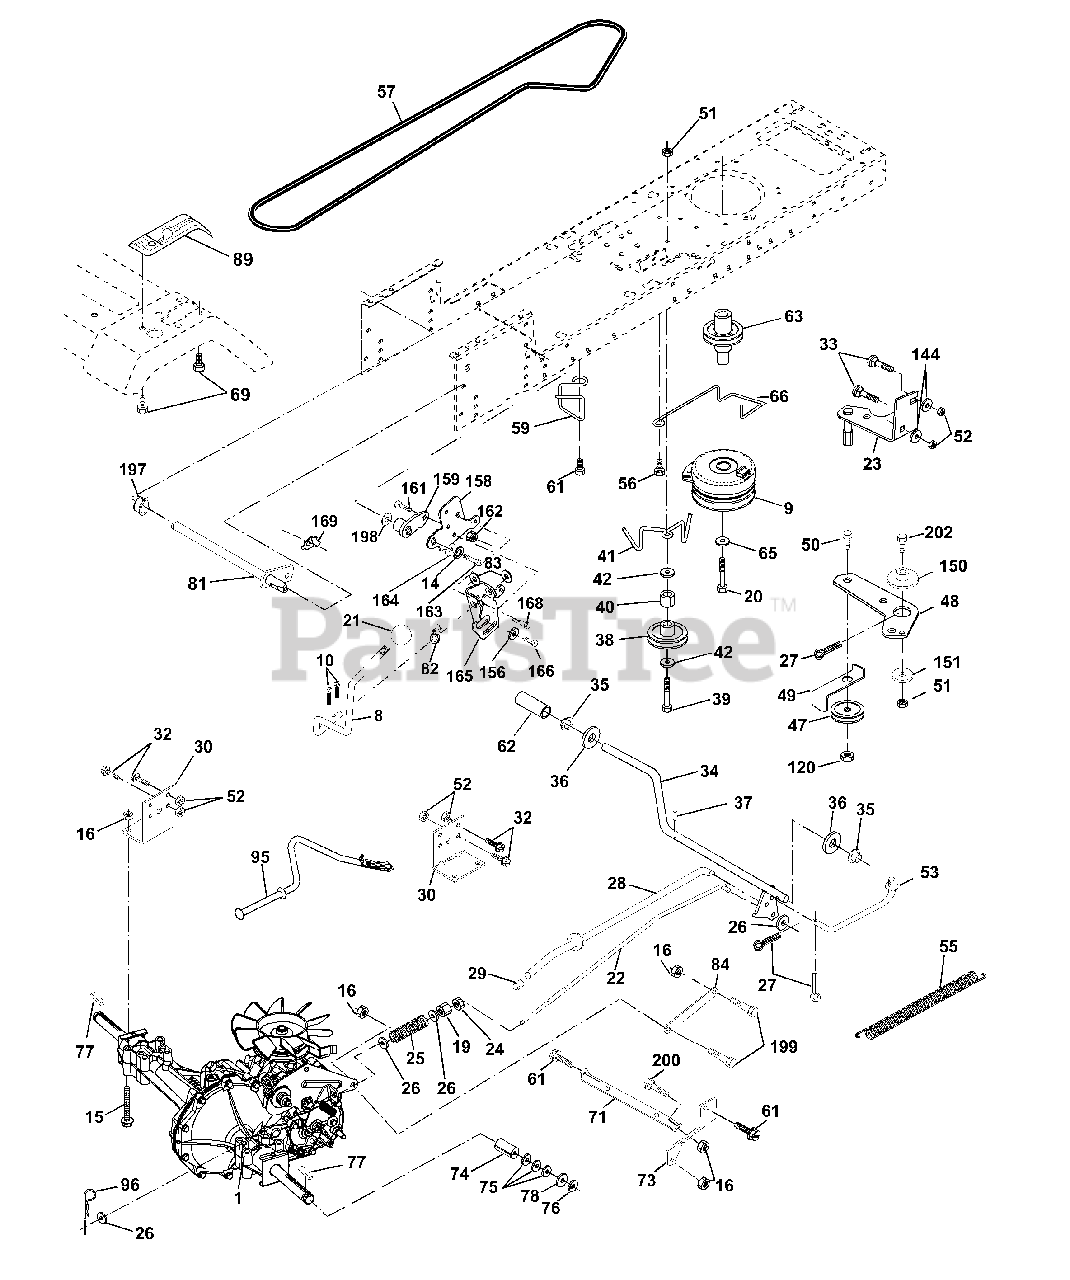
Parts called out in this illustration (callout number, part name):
8	Rod Shift Fender Adjust LT
9	Clutch Elecric
10	Pin Cotter 1/8 x 1 CAD
14	Washer Lock Hvy Helical
15	Bolt Hex 5/16-18 Gr. 5
16	Nut Lock Hex W/Ins. 5/16-18 Unc P
19	Nut Lock Hex W/Ins 3/8-16 Unc
20	Bolt, Hex 7/16-20 x 4-1/4 Ga. 5
21	Knob Deluxe 1/2-13 UNC BLK/BLK
22	Rod, Brake Hydro
23	Bracket Asm. Anti-Rot EVX
24	Nut Hex Jam 3/8-16 UNC
25	Spring, Brake Rod
26	Washer
27	Pin Cotter 1/8 x 3/4 CAD.
28	Rod, Parking Brake
29	Cap,Parking Brake
30	Bracket, Transaxle
32	Bolt Hex Hd 5/16-18 Unc x 3/4
33	Bolt Carriage 5/16-18 UNC x 3/4
34	Shaft, Foot Pedal
35	Bearing, Nylon
37	Pin, Roll
38	Pulley Flat Composite
39	Bolt Fin Hex 3/8-16 Unc x 3
40	Spacer Split
41	Keeper, Belt Idler
42	Washer 13/32 x 13/16 x 12 Ga
47	Pulley, Idler, V-Groove Plastic
48	Bellcrank Clutch Grnd Drv Stl
49	Retainer, Belt Style Spring
50	Bolt Hex Hd 3/8-16 Unc x 1-1/2
52	Nut Crown Lock 5/16-18
53	Link, Clutch
55	Spring, Return, Clutch
56	Screw 3/8-16 x 1.0
57	V-Belt, Ground Drive
59	Keeper, Center Span
61	Screw 3/8-16 x 3/4
62	Cover, Pedal
63	Pulley, Engine
65	Washer Lock Hvy HLCL Spr 7/16
66	Keeper Belt Engine
69	Screw Hex Wsh Hi-Lo 1/4-1/2 Unc
71	Strap Torque Lh
73	Strap Torque Rh
74	Spacer, Axle
75	Washer 25/32 x 1-1/4 x 16 Ga.
77	Key, Square
78	Washer 25/32 x 1-5/8 x 16 Ga
81	Shaft Asm Cross Tapered
82	Spring Torsion T/A
83	Washer 17/32 x 3/4 x 16 Ga.
84	Link Transaxle
89	Console, Hydro
95	Control Asm. Bypass Hydro
96	Retainer Spring 1" Zinc/Cad
120	Nut Lock Flg. 3/8-16 Unc
144	Washer 11/32 x 5/8 x 16 Ga.
150	Spacer Retainer
151	Washer 13/32 x 2 x 10 Ga.
156	Washer Srrted 5/16 ID X 1 X .125
158	Bracket Shift Mount
159	Hub Tapered Flange Shift LT
161	Bolt Rdhd Sqnk 1/4-20 x 3/4 Gr. 5
162	Nut Crownlock 1/4-20 Unc
163	Bolt Hex Fin 1/4-20 Unc x 1 Gr. 5
164	Washer 5/8 x .281 x 10 Ga.
165	Bracket Pivot Lever
166	Screw 5/16-18 x 5/8
168	Bolt Shoulder 5/16-18 x .561
169	Plate Fastening LT
197	Nyliner Snap-In 5/8" ID
198	Washer Nyl 7/8ID x .105 Hyd
199	Bolt Shoulder 5/16-18 Unc
200	Bolt Rdhd Sqnk 5/16-18 Unc x 1
